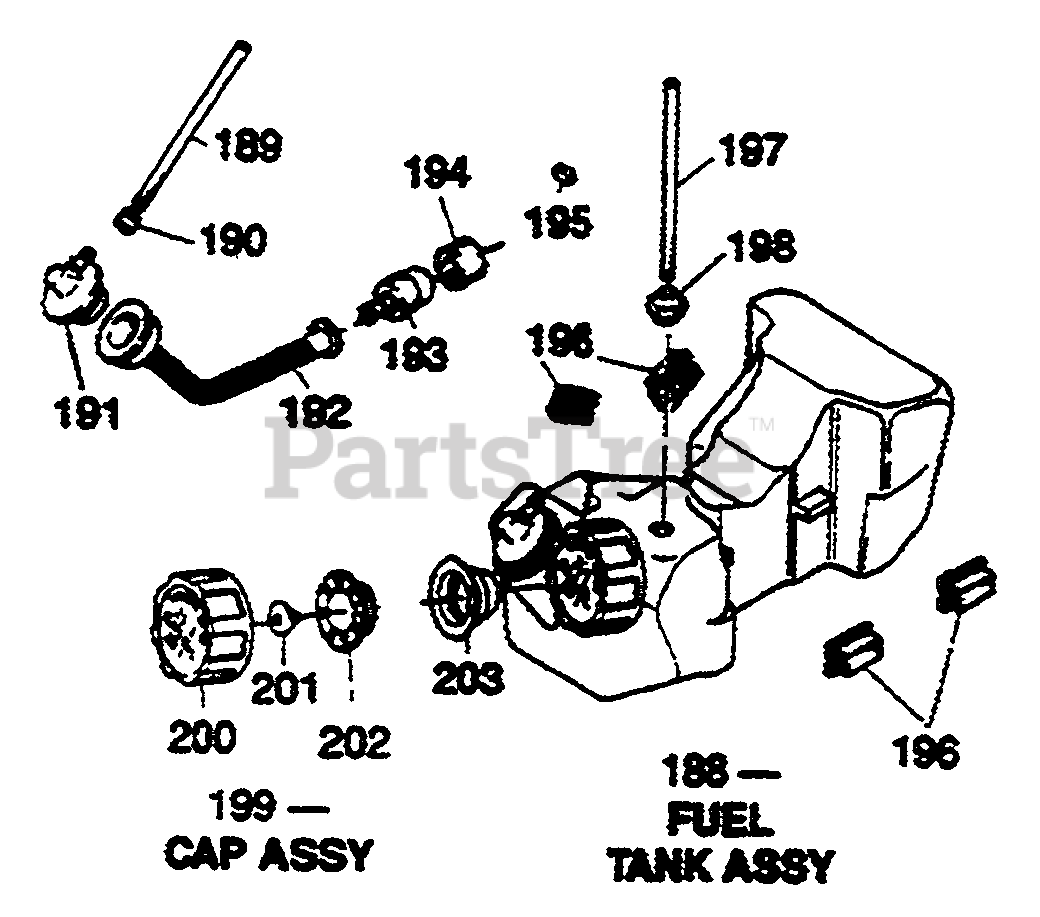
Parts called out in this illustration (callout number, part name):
188	FUEL TANK ASSY
189	TUBE, FUEL
192	HOSE,SUCTION
193	FILTER, FUEL
197	TUBE,FUEL
199	TANK CAP ASSY
201	VALVE, BREATHER
